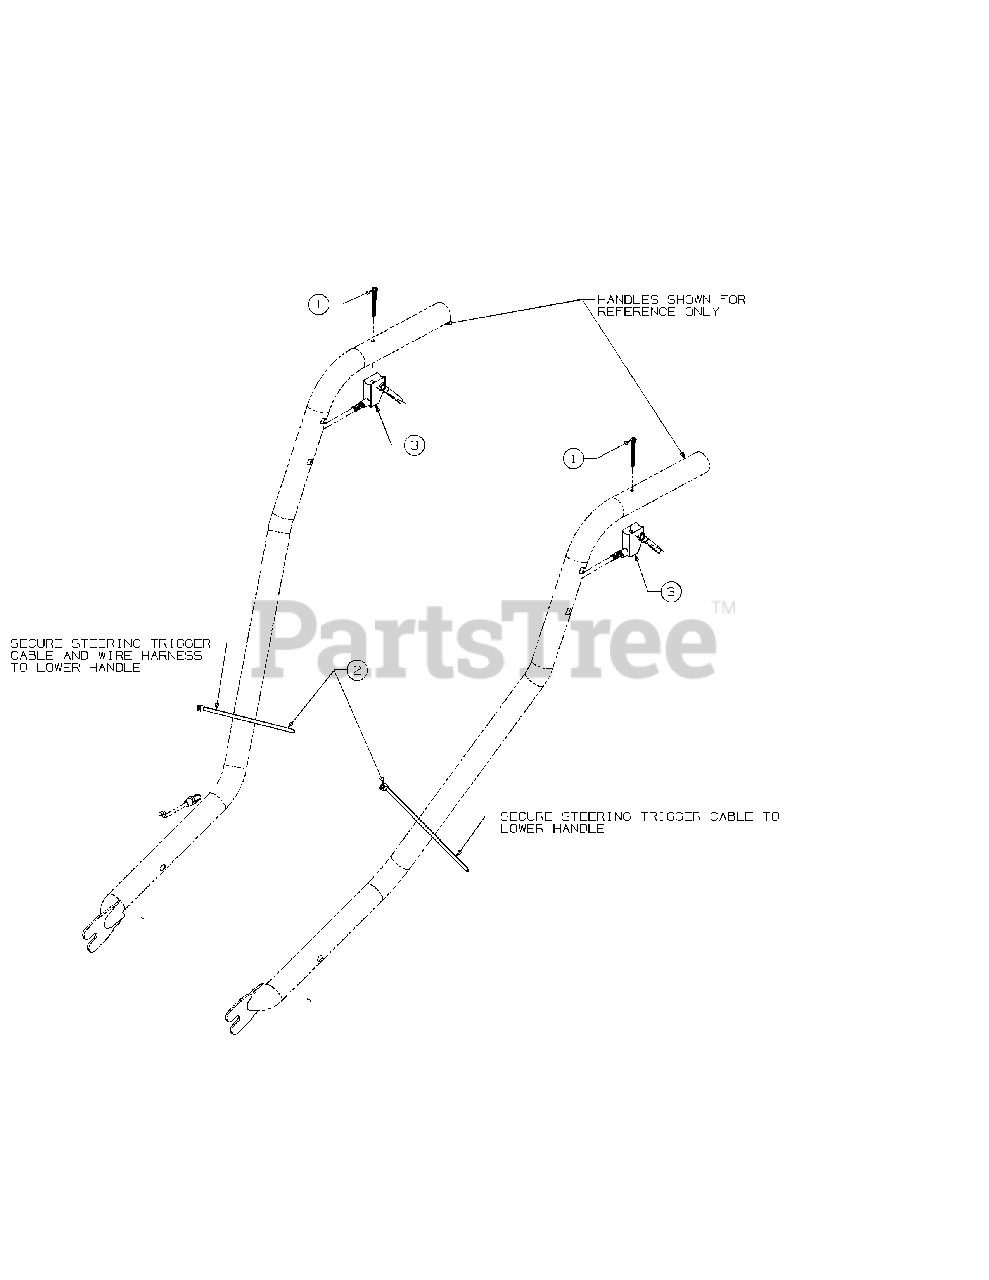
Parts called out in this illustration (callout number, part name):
1	Screw-Oval C/Sunk
2	Tie-Cable 7"
3	Control-Trigger
